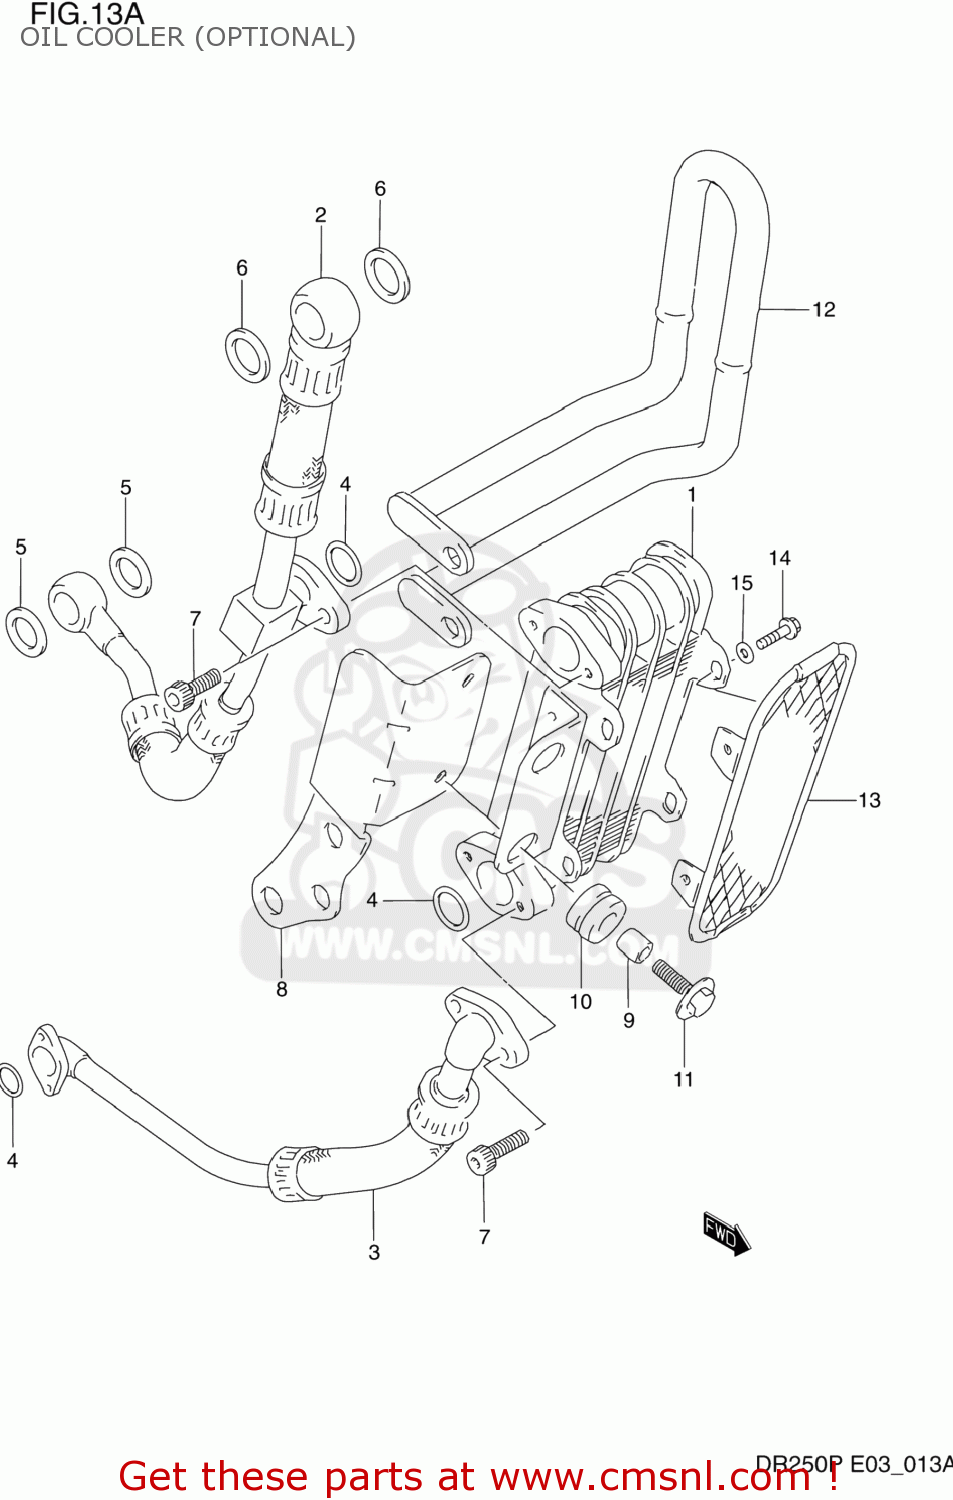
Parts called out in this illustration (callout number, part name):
1	COOLER ASSY,OIL
2	HOSE,OIL COOLER UPR
3	HOSE,OIL COOLER LWR
4	O RING(D:2.4,ID:12.3)
5	GASKET(12X16.5X1.5) (NAS)
6	GASKET(16X22X2) (NAS)
7	BOLT
8	BRACKET,OIL COOLER
9	SPACER (6.8X10X10)
10	CUSHION
11	BOLT 6X20
12	GUARD,OIL COOLER
13	BUMPER,OIL COOLER
14	BOLT
15	WASHER,LOCK
